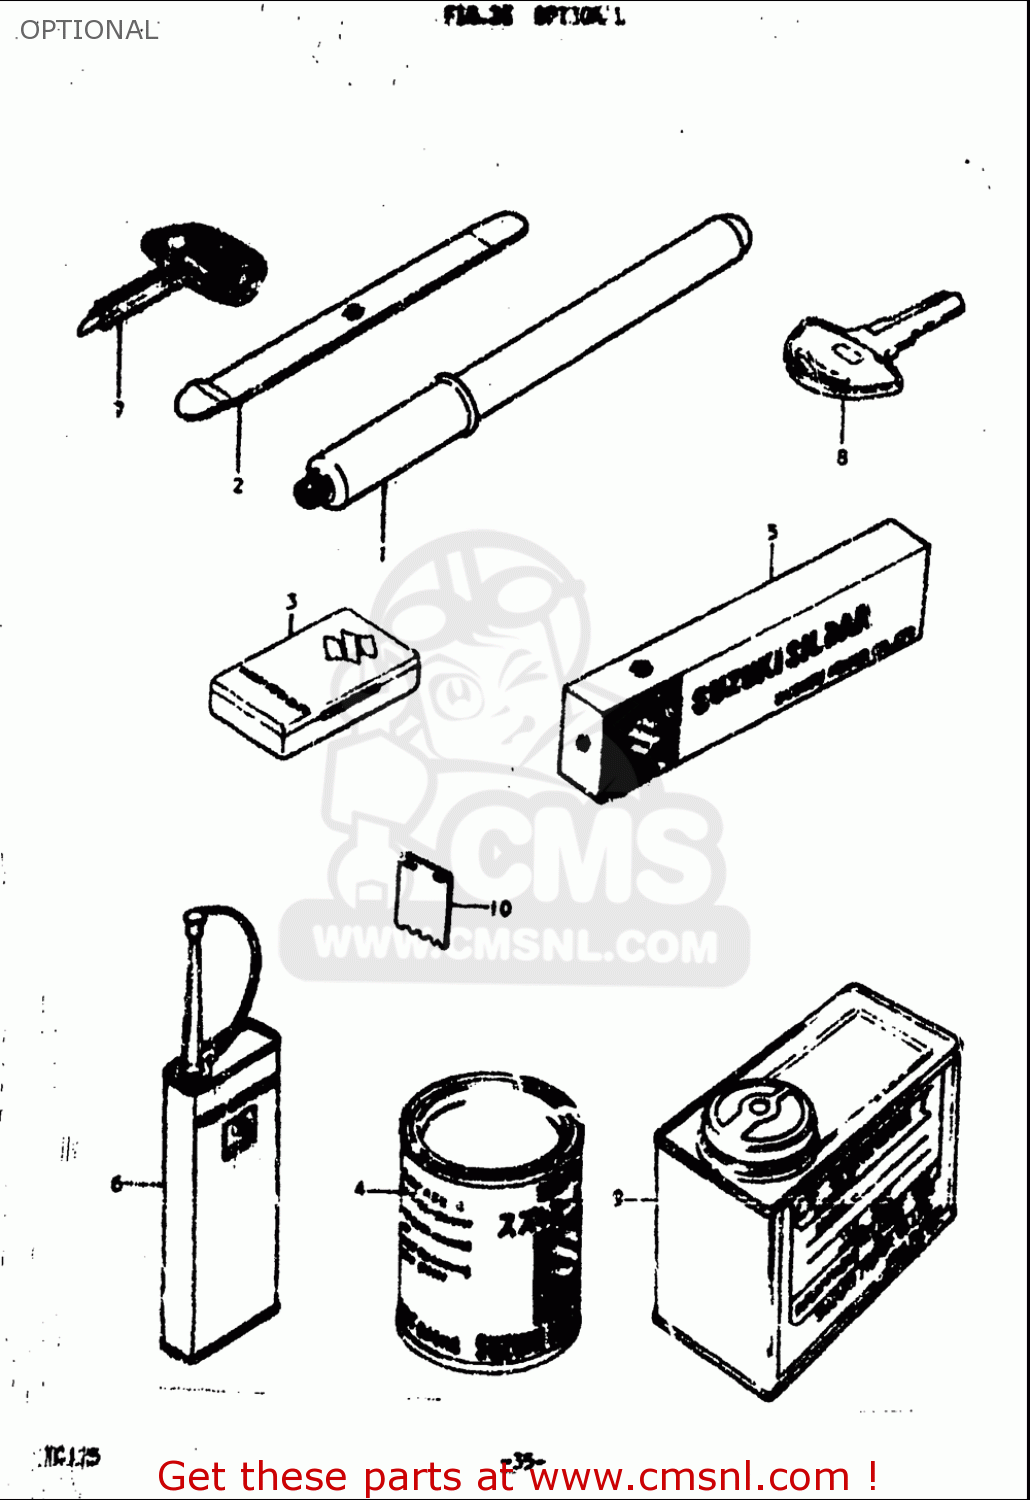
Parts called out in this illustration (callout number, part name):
2	LEVER,TIRE
4	GREASE(C)EP2 LITHIUM 150G
6	THREAD LOCK NO.1401 CLEAR 200G
8	KEY,BLANK
10	GASKET SET (MCA)
